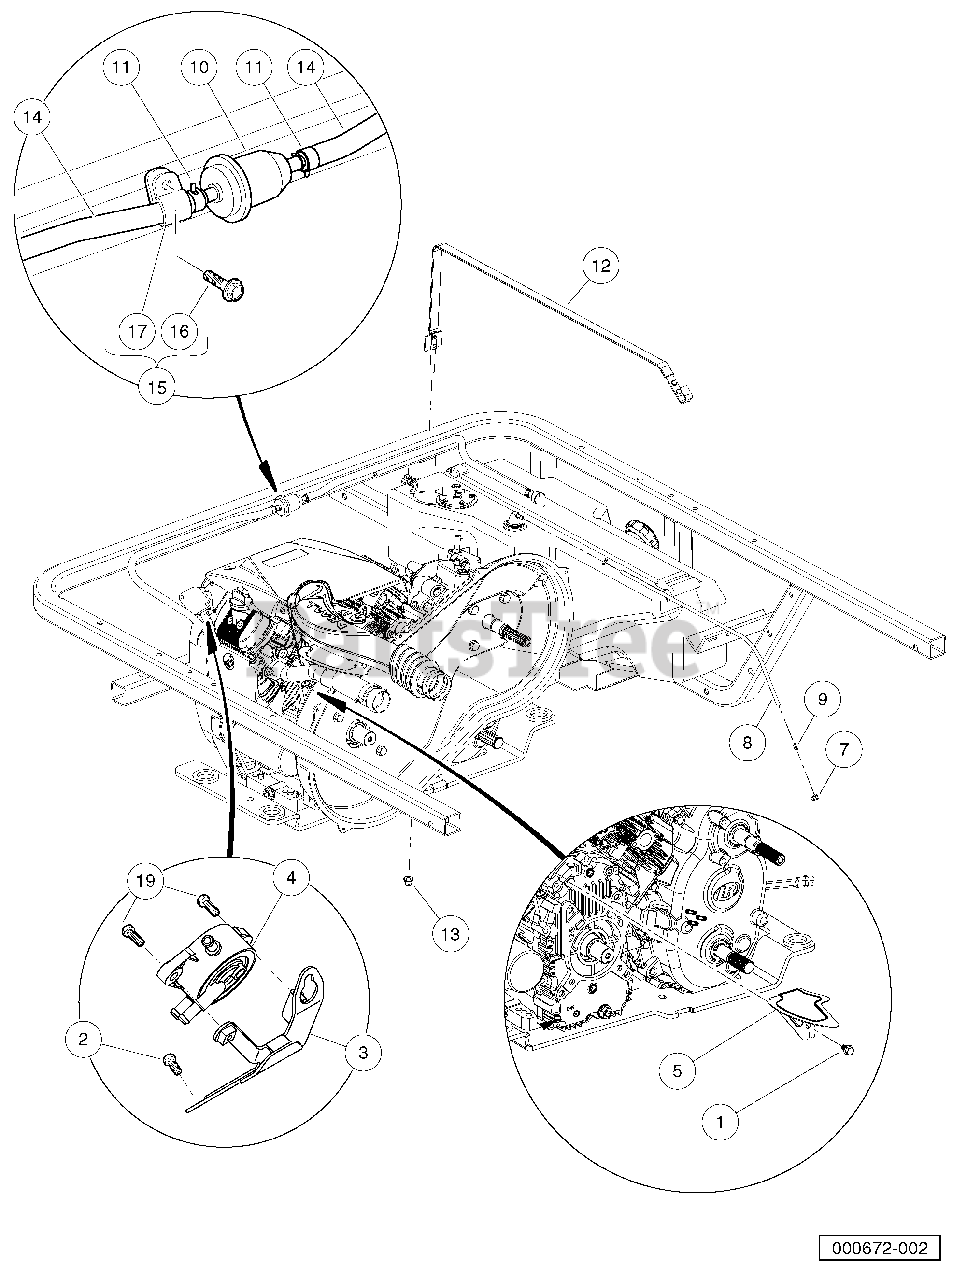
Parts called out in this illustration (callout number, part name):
1	Bolt Flanged Head, M8 X1.25x 16 with Loctite
2	Bolt, Flg, M6 X 1.0 X 16
3	Bracket, Fuel Pump, Fh
4	Pump, Fuel, Impulse, Fh
5	Heat Shield, Header, Gas
6	Instl, Fuel System, Fh680d
7	Clamp, 0.301 ID Hose
8	Hose, Fuel, Vent, 22" Long
10	Filter, Fuel, 30 Micron
11	Clamp, Hose, Ctb 13mm
12	Strap, Tank, Fuel
13	Lock Nut, Flg M8 X 1.25 Nylon
15	Kit, Fuel Line Clamp, 4x4 Khi
16	Screw, M8X1.25X30, Hex
17	P-clamp, Insulated 0.625 In
18	Instr, Kit Fuel Line 4x4 Khi
19	Bolt, Flanged, M6 X 20, Kaw
